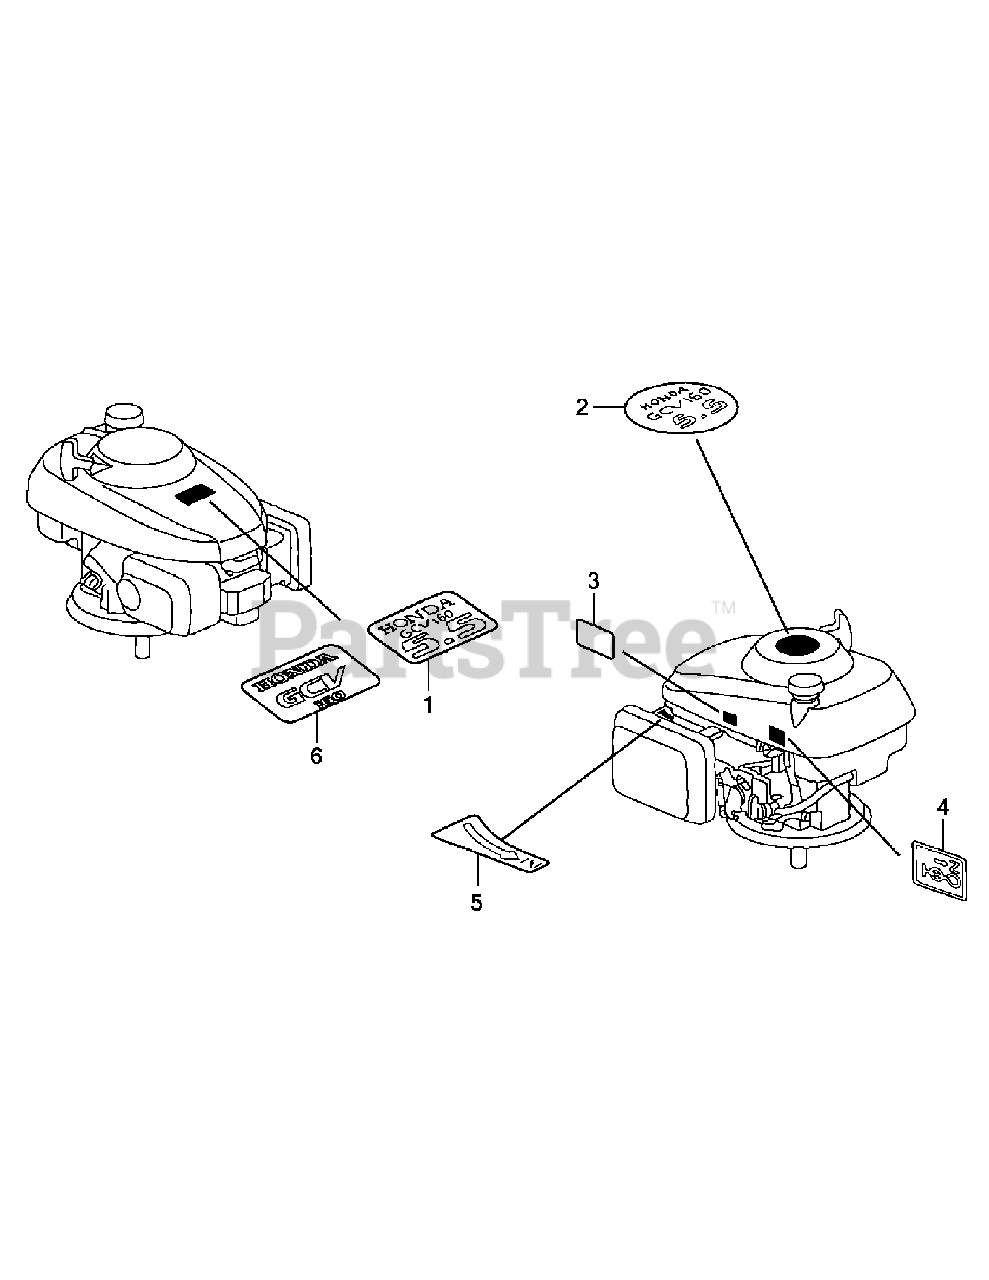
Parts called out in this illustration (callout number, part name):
1	PRI; EMBLEM (GCV160)
3	LABEL, WARNING
4	MARK, CHOKE
